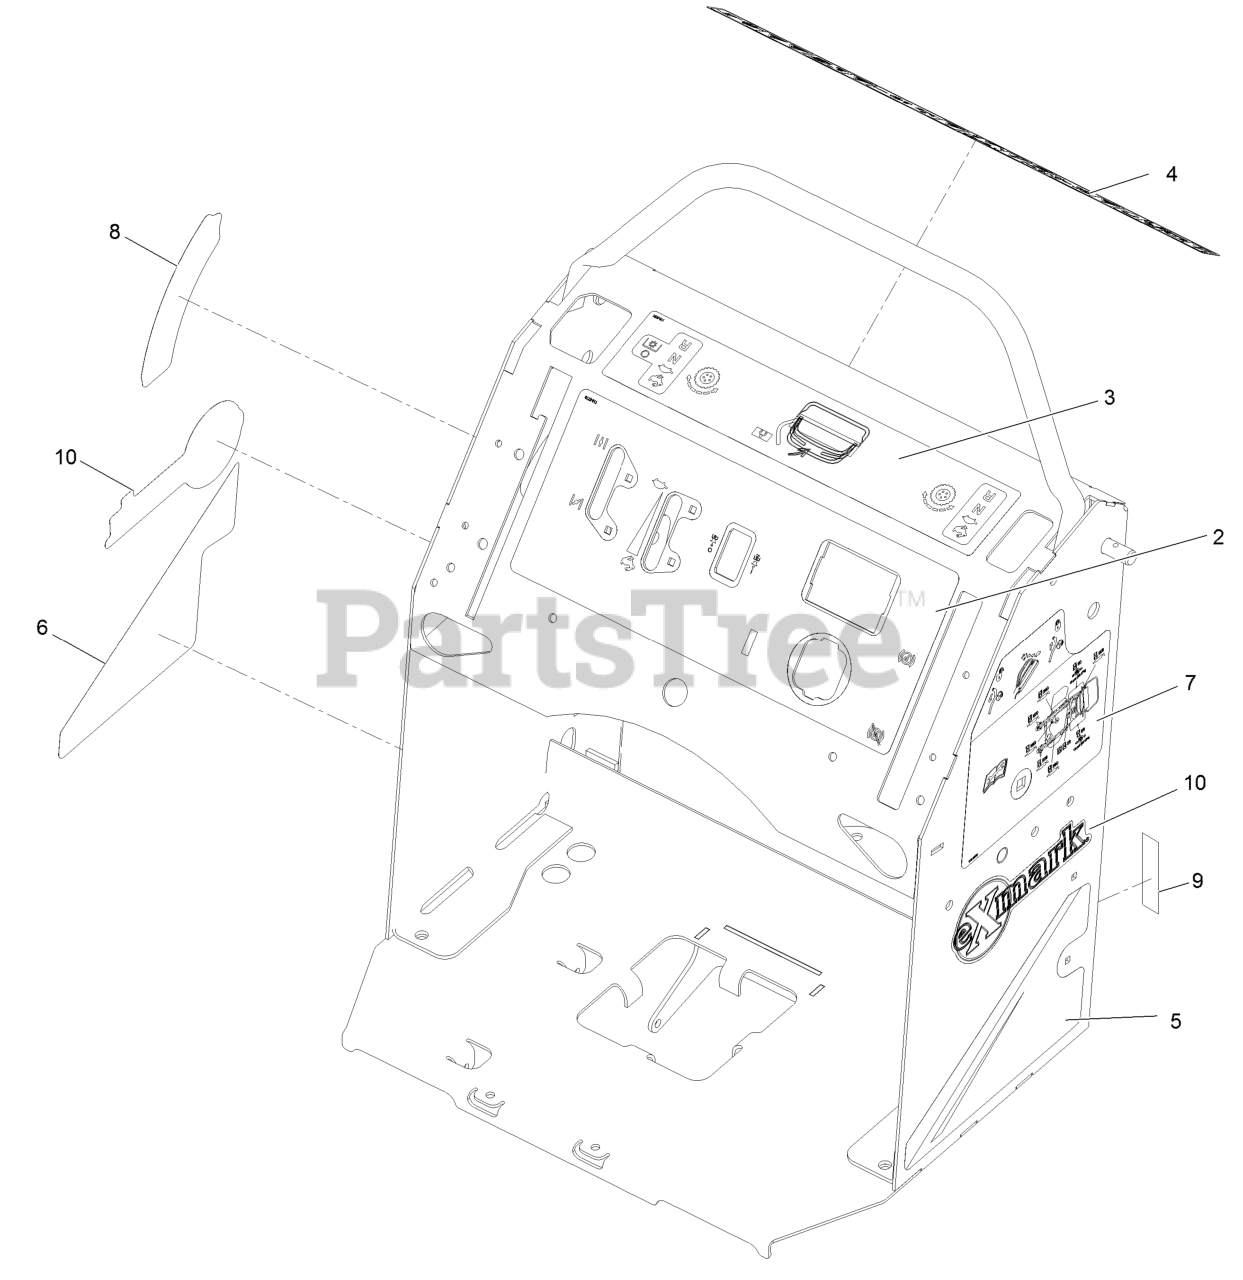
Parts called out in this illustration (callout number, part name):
2	DECAL-CONTROL PANEL
3	DECAL-MOTION CONTROL
4	DECAL-WARNING
5	DECAL-LH PANEL
6	DECAL-RH PANEL
7	DECAL-SERVICE AID
8	DECAL-HEIGHT OF CUT
9	DECAL-FUSE
10	DECAL-EXMARK LOGO
